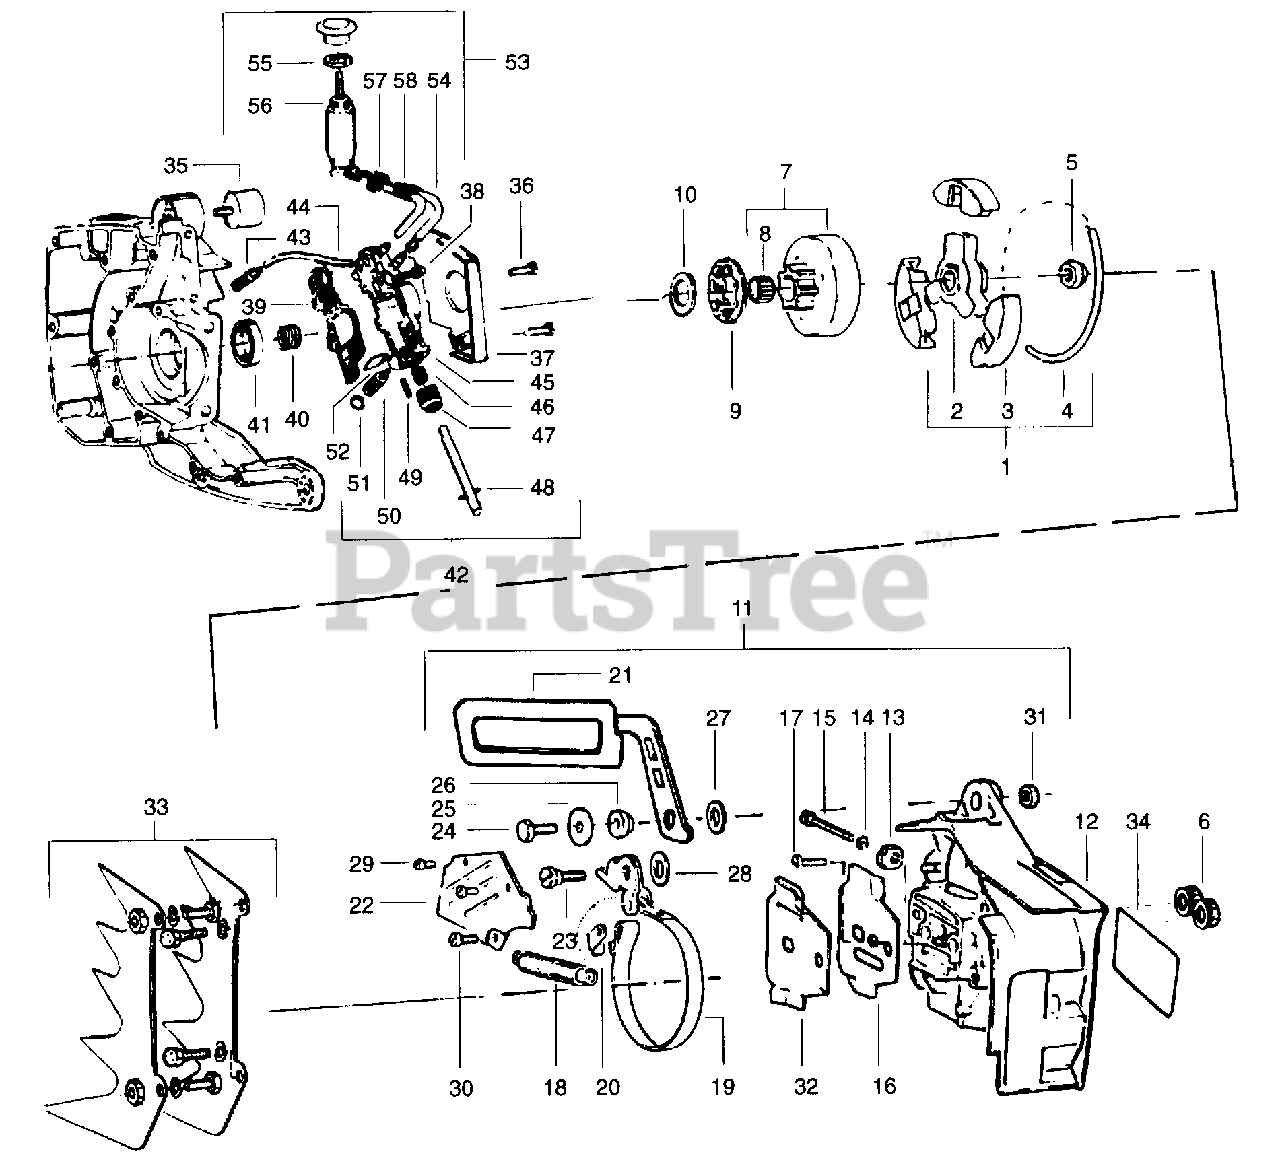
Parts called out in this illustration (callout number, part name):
1	Clutch Ass'y. (incl. 2-4)
2	Clutch Driver
3	Clutch Shoe
4	Clutch Spring
6	Strut Nut
7	Clutch Drum & Bearing
9	Rim Segment 3/8 7T
9	Rim Segment 404 7T
10	Thrust Washer
11	Brake Ass'y. (lncl. 13-31)
12	Clutch Cover & Tensioner
14	Retaining Ring
16	Outer Guide Plate
17	Terminal Screw
19	Cam/Band Ass'y.
20	Locking Plate
21	Kickback Guard Ass'y.
22	Cover Ass'y.
32	Inner Guide Plate
33	Bucking Spur (Incl.screws, washers, 2 spurs) Northeast Style
33	Bucking Spur (Incl.screws, washers, 2 spurs) Smaller Style
34	Side Decal
35	Shock Absorber
37	Dirt Shield
40	Wire Worm
42	Oil Pump Ass'y. w/ Manual Overide (Incl. 43, 44, 46,47,49-52)
43	Inlet Tube
44	Oil Pump Body
45	Plunger Spring
46	Oil Pump Gear
47	Plunger Ass'y.
48	Roll Pin
49	Adj. Screw
51	Oil Pump Seal
52	Oil Pump Ass'y. (Incl. 54-58)
55	Manual Oil Pump
56	Speed Clip
57	Oil Hose
